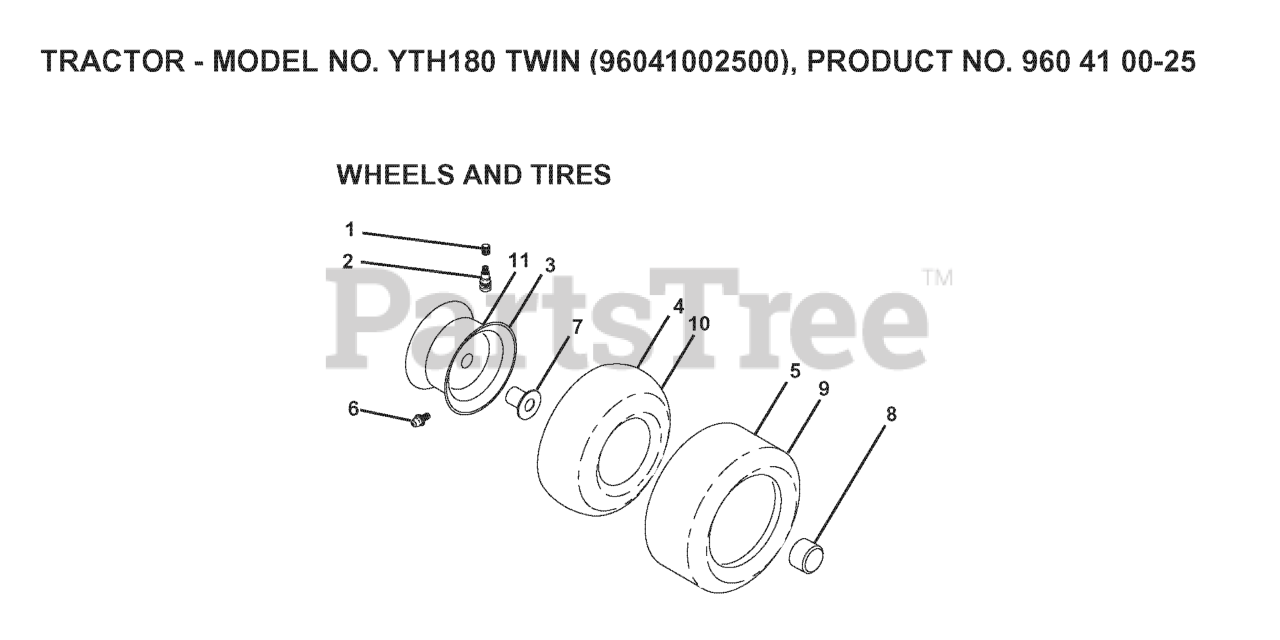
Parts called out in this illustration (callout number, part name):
2	VALVE STEM LT
3	RIM ASM 6" FRONT SILVER
4	TUBE.5.3/4.5/6
5	TIRE HEAVY DUTY
6	FITTING LT
7	BEARING T
8	CAP, AXLE BLK
9	TIRE.TS.20X10-8
10	TUBE
11	RIM ASM 8" REAR SILVER
